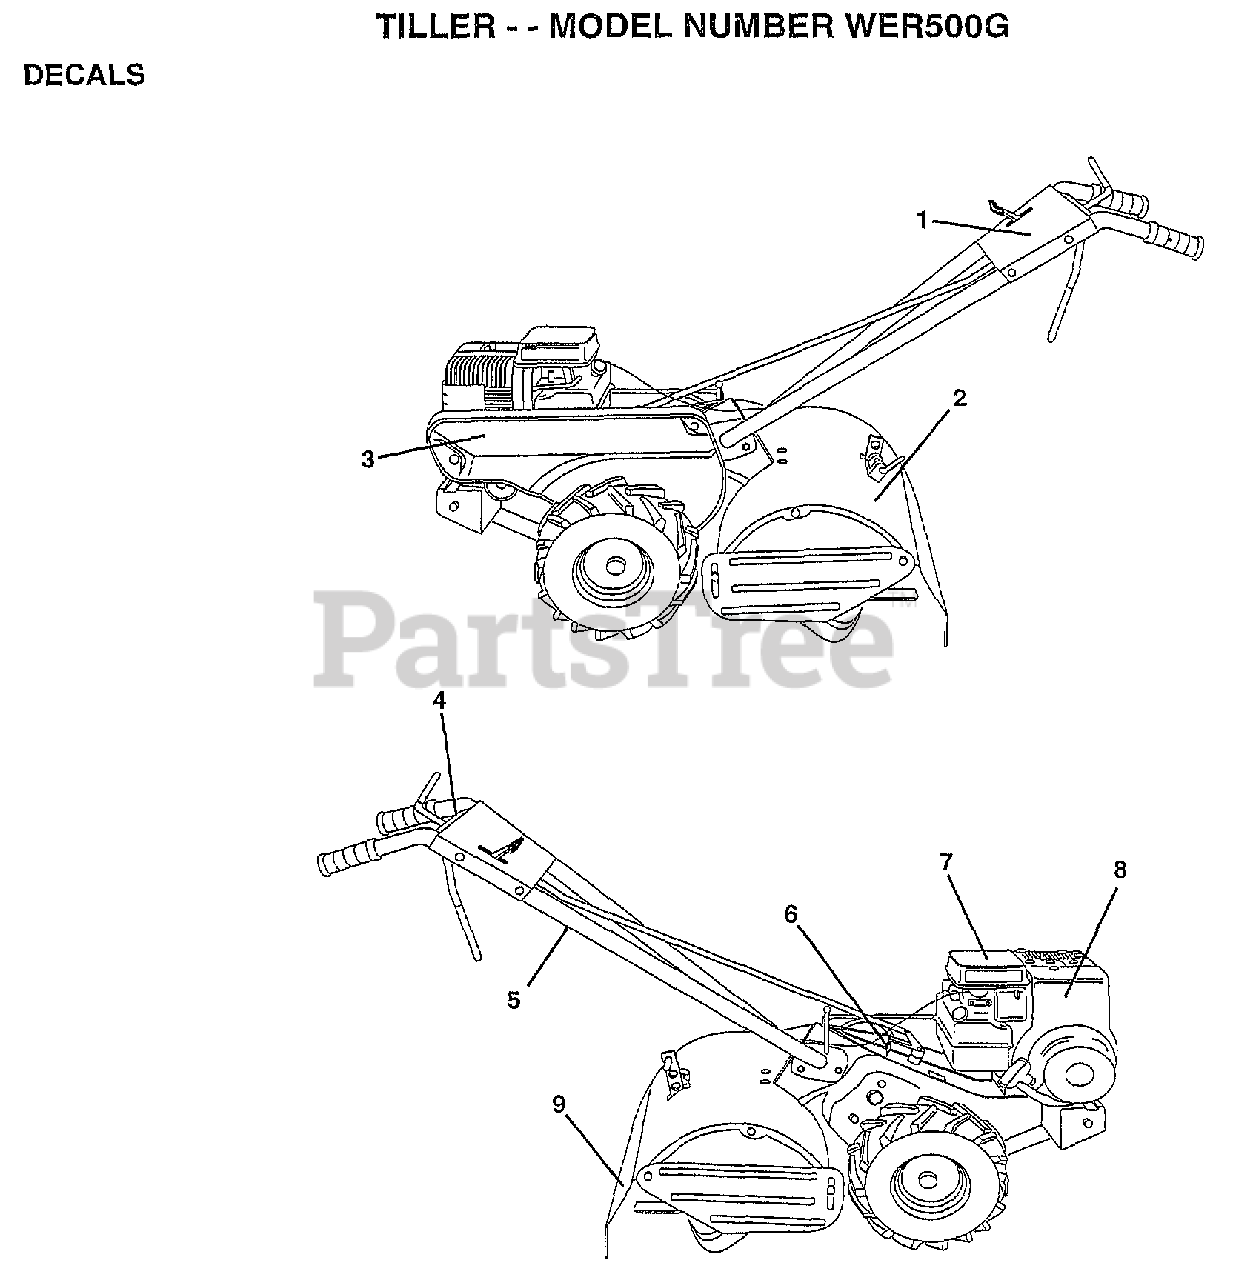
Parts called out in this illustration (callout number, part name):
1	DECAL LOGO 17 5HP
2	DECAL SHIELD TINE
3	DECAL BELT GUARD
5	DECAL TI
7	DECAL TI
8	DECAL, BRIGGS & STRATTON
